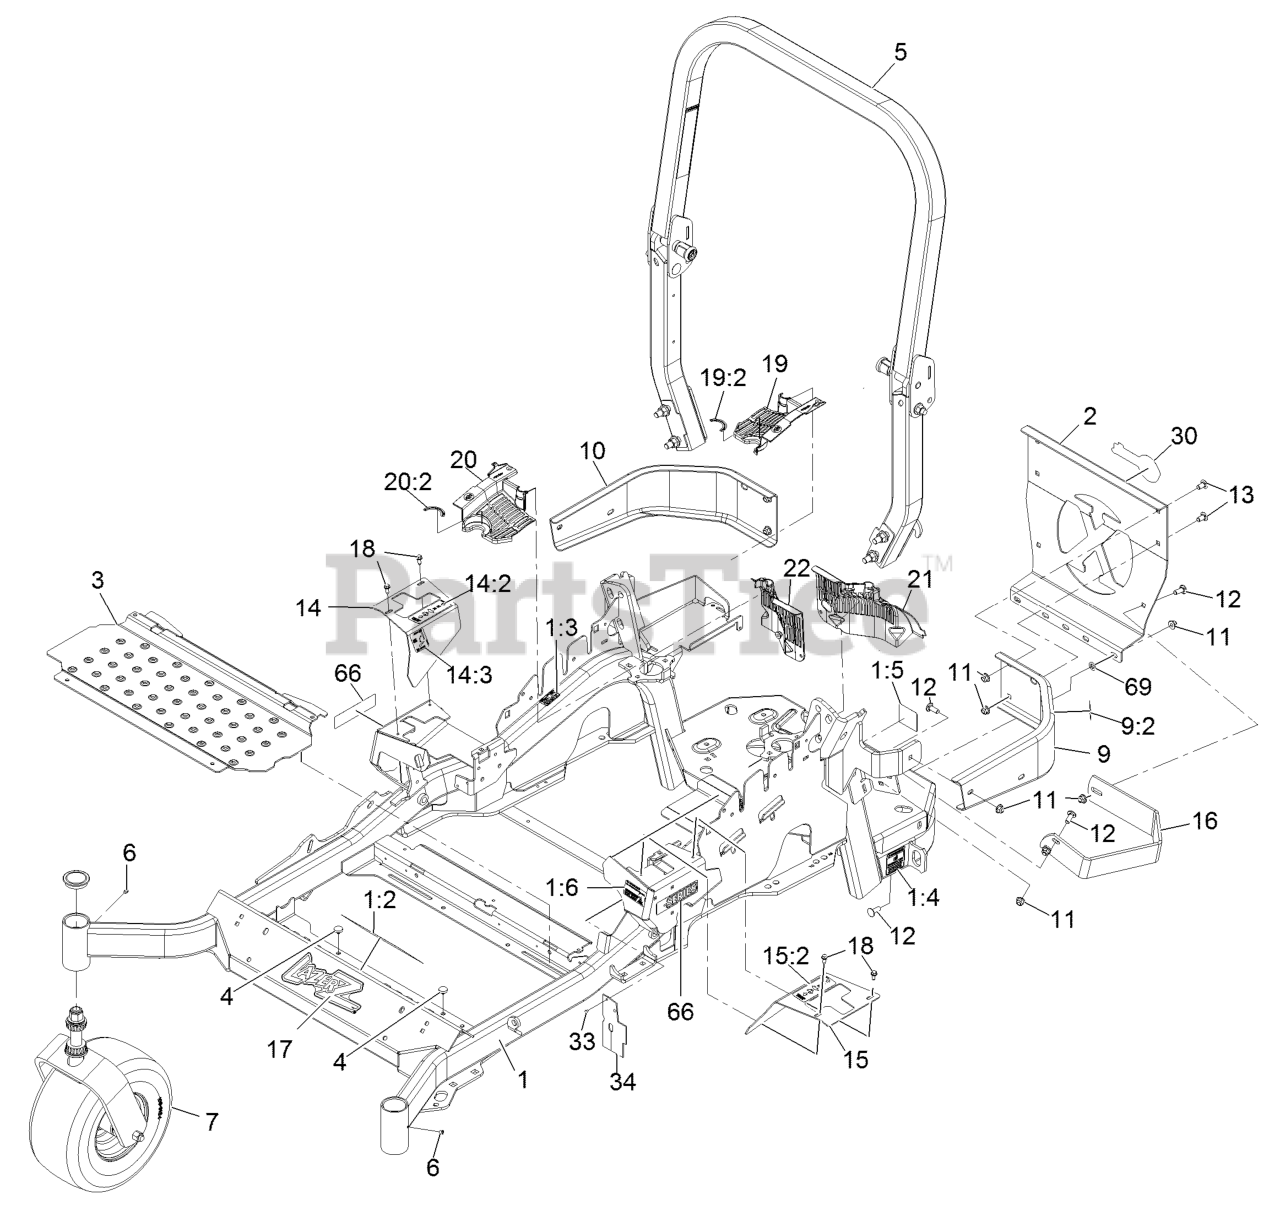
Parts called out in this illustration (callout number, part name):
1	MAINFRAME ASM
1:2	DECAL-SLOPE
1:3	DECAL-CAUTION
1:4	DECAL-BELT DRIVE
1:5	DECAL-SPARK ARRESTER
1:6	DECAL-FUEL FILL
2	PLATE,REAR GUARD
5	ROPS ASM
7	Asm,Front Caster W/Fork
9	LH BUMPER ASM
9:2	DECAL-CAUTION
10	BUMPER-RH
11	NUT-HF, NI
12	SCREW-CARR
13	SCREW-CARR
14	RH MOTION CONTROL COVER ASM
14:2	DECAL-MOTION CONTROL
14:3	DECAL-PARK BRAKE
15	LH MOTION CONTROL COVER ASM
15:2	DECAL-MOTION CONTROL
17	DECAL,LAZER MODEL
18	SCREW-HWH
19	LH HYDRO GUARD ASM
19:2	DECAL-HYDRO OIL
20	RH HYDRO GUARD ASM
20:2	DECAL-HYDRO OIL
21	GUARD-HYDRO, REAR (LH)
22	GUARD-HYDRO, REAR (RH)
33	RIVET-POP
34	DEFLECTOR-AIR FLOW
66	DECAL-E-SERIES
69	NUT-PUSH
